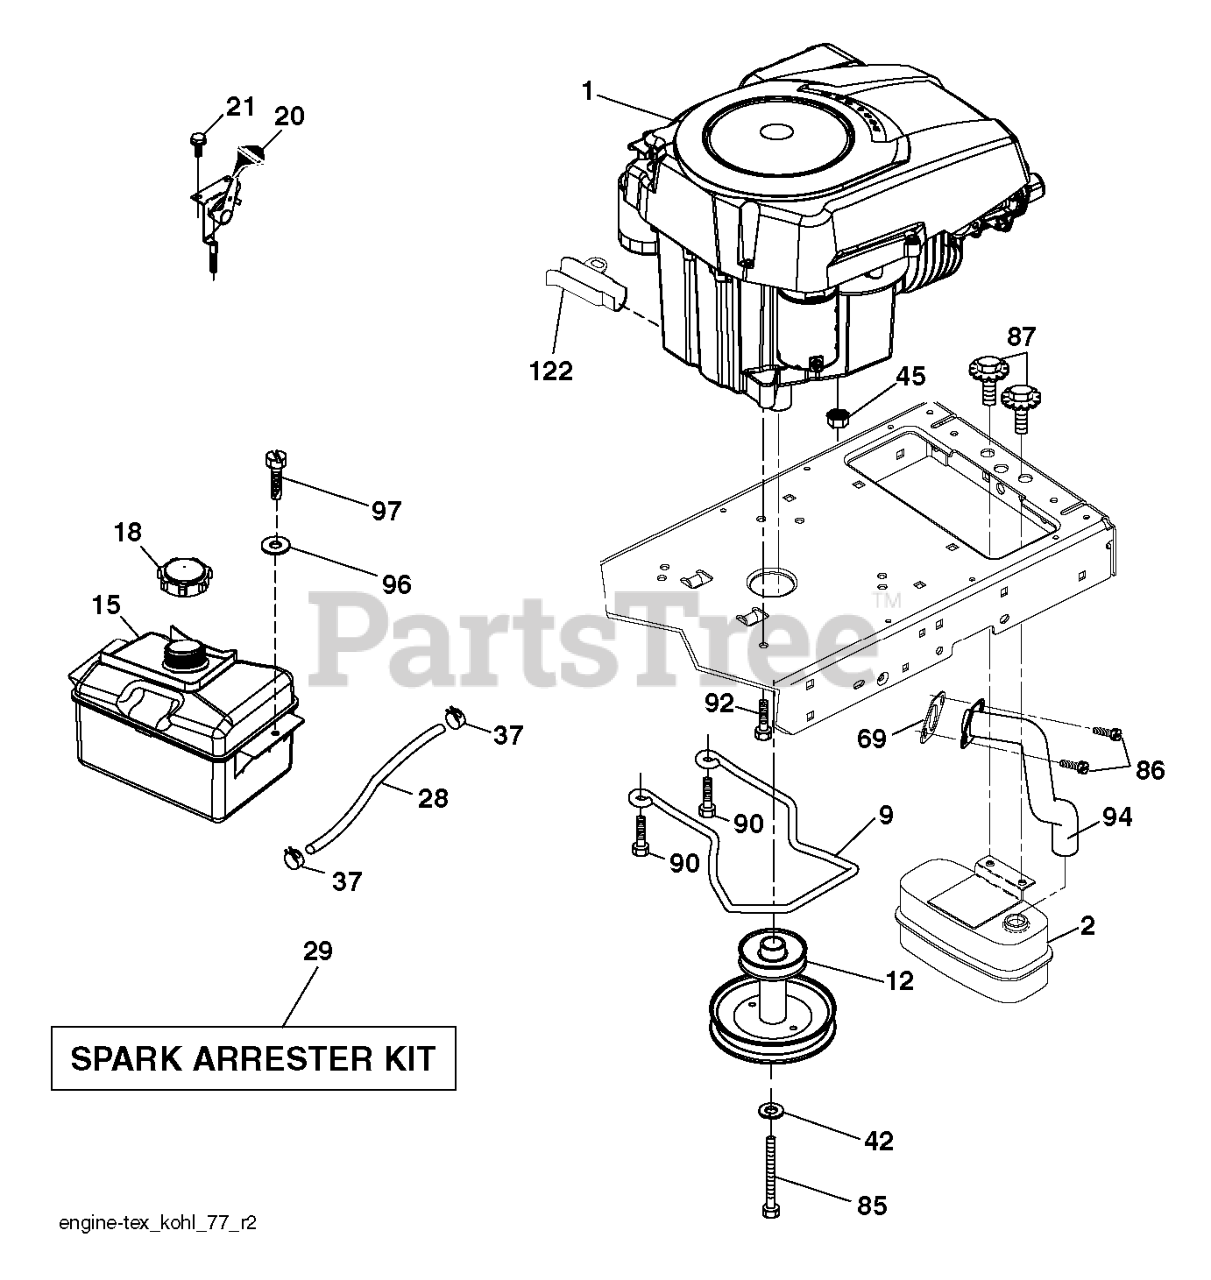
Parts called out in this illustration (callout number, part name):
2	MUFFLER.ASM.SNGL.XTNDED.DFLCTR
9	KEEPER.BELT.ENG.3.25"2BOLT.PNT
12	PULLEY.ENGINE
15	FUEL.TANK.ASM.NON-EPA
18	CAP ASM.FUEL.2.25"FR.
20	THROTTLE.COBRA.21".RSTART.BLK
21	SCREW.#10 X 0.750.BOS
28	LINE.FUEL.20
29	KIT.SPARK ARRESTOR 794945 B&S
37	HOSE CLAMP
42	WASHER 7/16 LOCK
45	NUT
69	GASKET.EXHAUST.KOHLER
85	BOLT.HEX.7/16-20X4.GR5.1.5BLUE
86	NUT.HEX.FLANGE.TOPLOCK
87	BOLT.5/16-18UNCX3/4 W/SEMS.BLK
90	SCREW 3/8-16X1
92	SCREW 3/8-16X1
94	TUBE.EXHAUST.KOHLER 5400
96	WASHER
97	SCREW HEXWSHR 1/4-20X3/4
122	EXTENSION DRAIN OIL
